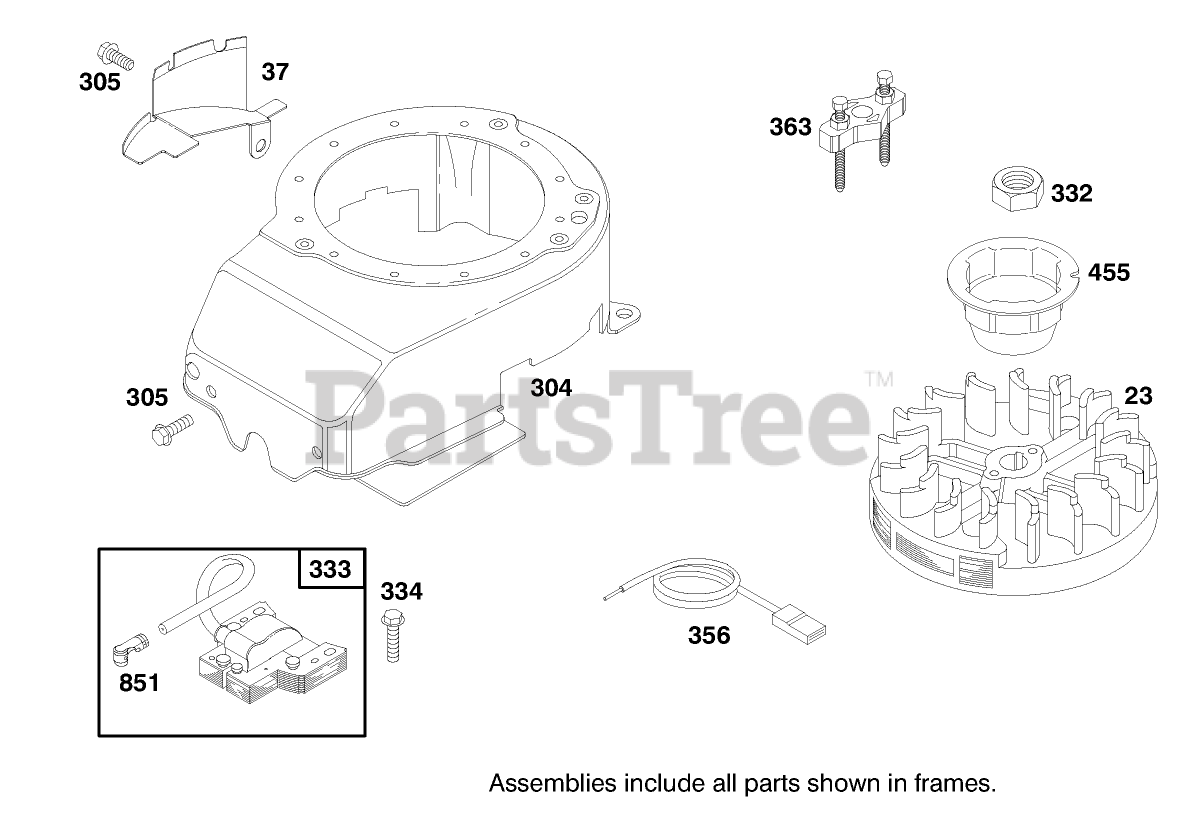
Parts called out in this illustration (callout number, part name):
23	Flywheel
37	Flywheel Guard
304	Housing-Blower
305	Screw-Hex
333	Armature-Magneto
334	Screw-Sem
356	Wire Stop
363	Puller-Flywheel
851	Terminal-Spark Plug
